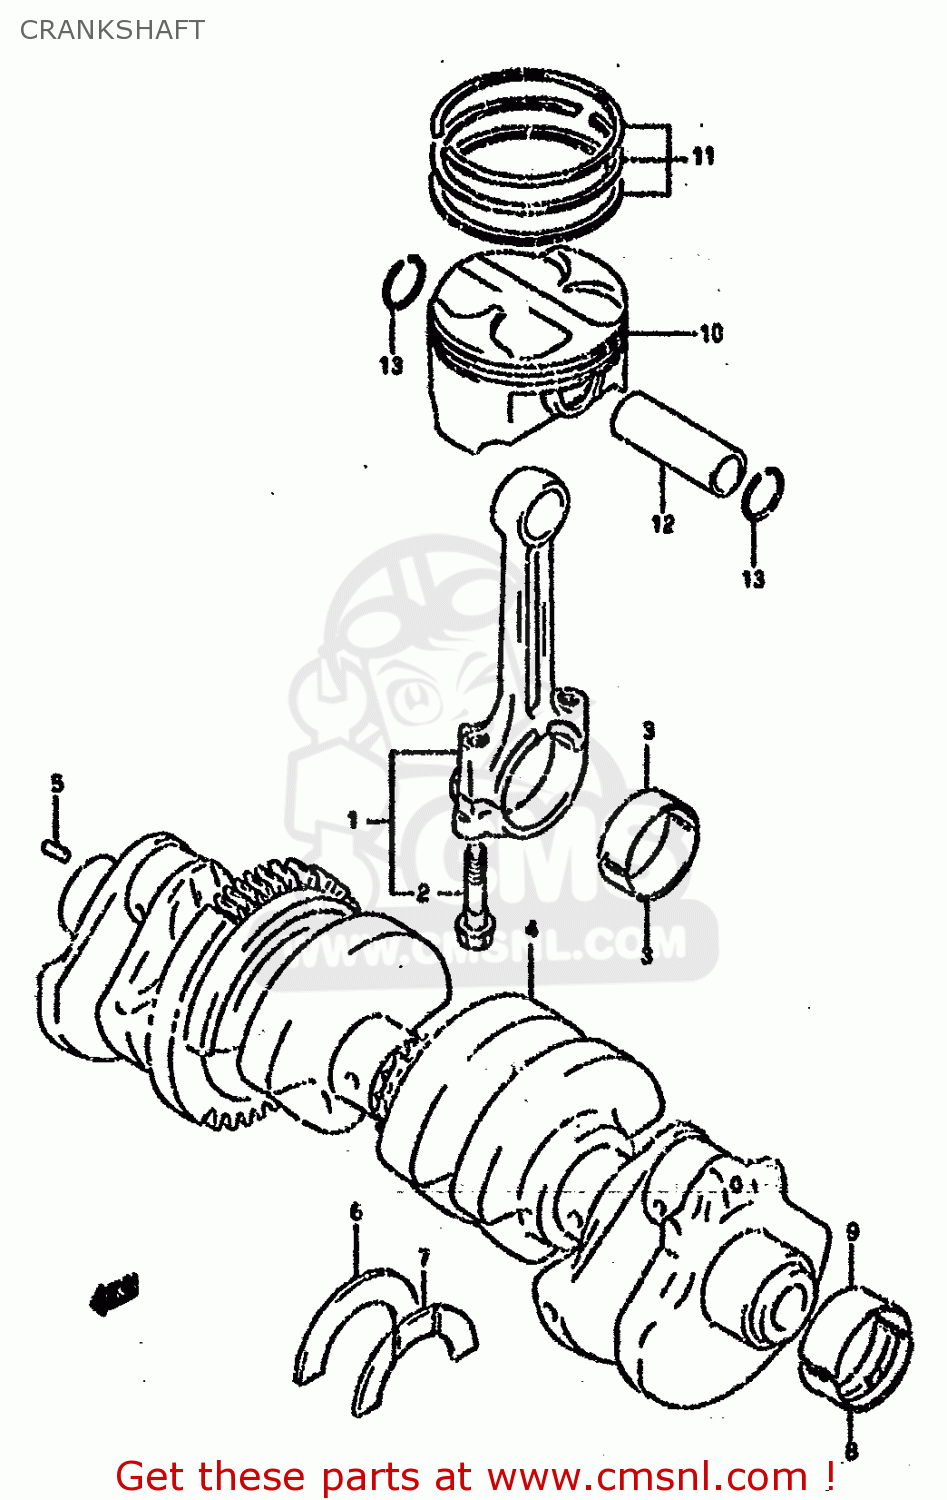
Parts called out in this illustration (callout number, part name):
1	CONNECTING ROD ASSEMBLY
2	BOLT,CONNECTING ROD
3	BEARING,CRANK PIN
4	CRANKSHAFT SET
5	PIN
6	BEARING,CRANK THRUST(GREEN)
7	BEARING,CRANK THRUST(RED)
8	BEARING,CRANKSHAFT(GREEN)
9	BEARING,CRANKSHAFT(GREEN)
10	PISTON
11	RING SET,PISTON
12	PIN,PISTON
13	CIRCLIP
